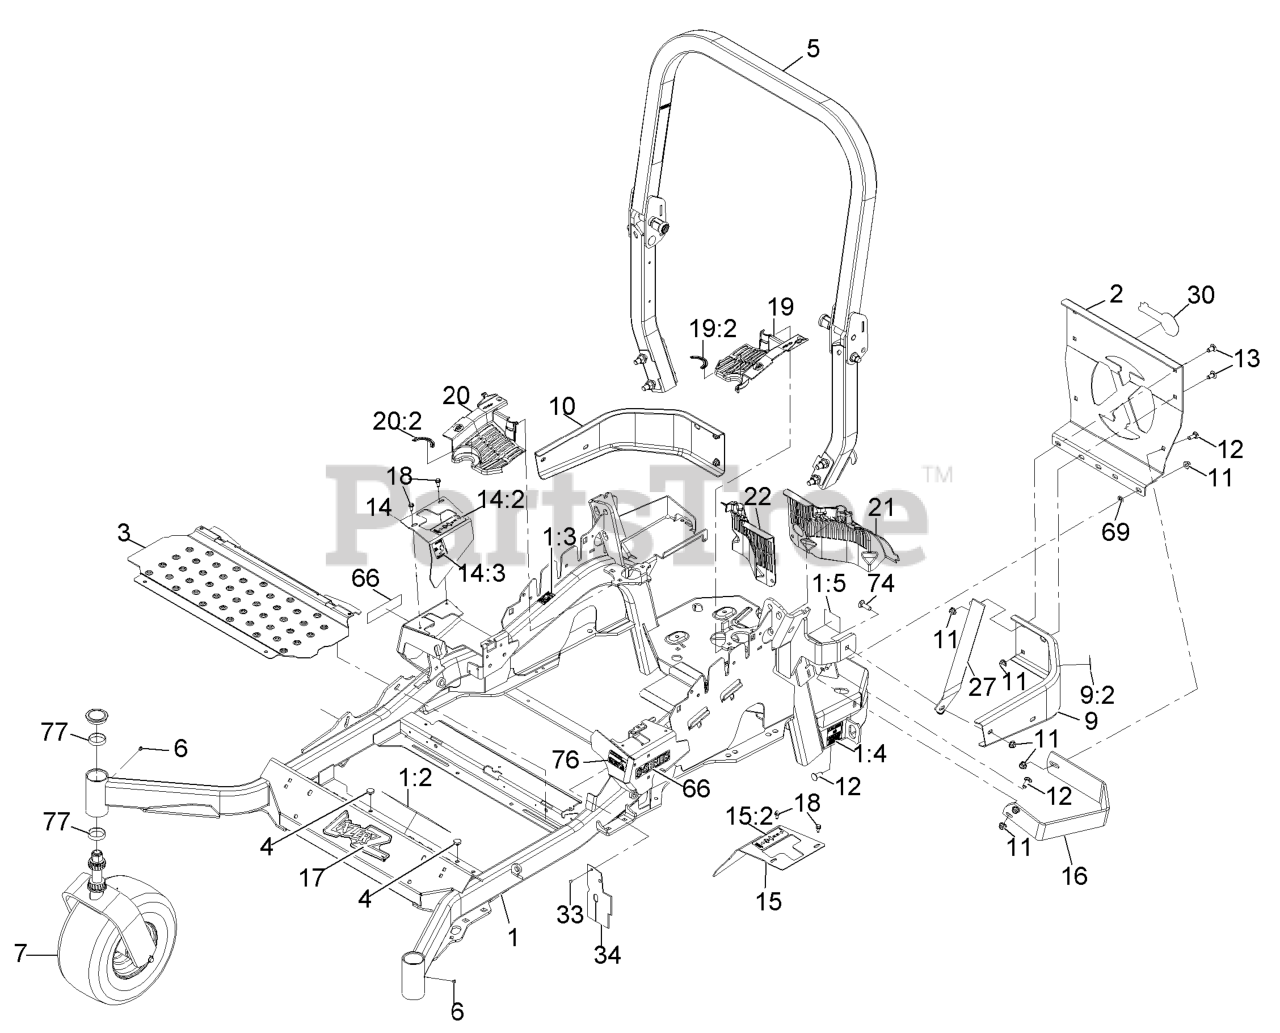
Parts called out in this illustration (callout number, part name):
1	MAINFRAME ASM
1:2	DECAL-SLOPE
1:3	DECAL-CAUTION
1:4	DECAL-BELT DRIVE
1:5	DECAL-SPARK ARRESTER
2	PLATE,REAR GUARD
5	ROPS ASM
7	LH BUMPER ASM
9	DECAL-CAUTION
9:2	BUMPER-RH
10	NUT-HF, NI
11	SCREW-CARR
12	SCREW-CARR
13	RH MOTION CONTROL COVER ASM
14	DECAL-MOTION CONTROL
14:2	DECAL-PARK BRAKE
14:3	Decal-Park Brake
15	LH MOTION CONTROL COVER ASM
15:2	DECAL-MOTION CONTROL
16	GUARD-MUFFLER
17	DECAL,LAZER MODEL
18	SCREW-HWH
19	LH HYDRO GUARD ASM
19:2	DECAL-HYDRO OIL
20	RH HYDRO GUARD ASM
20:2	DECAL-HYDRO OIL
21	GUARD-HYDRO, REAR (LH)
22	GUARD-HYDRO, REAR (RH)
33	RIVET-POP
34	DEFLECTOR-AIR FLOW
66	DECAL-E-SERIES
69	NUT-PUSH
74	BOLT-CARR
76	DECAL-FUEL FILL
77	CUP-BEARING
